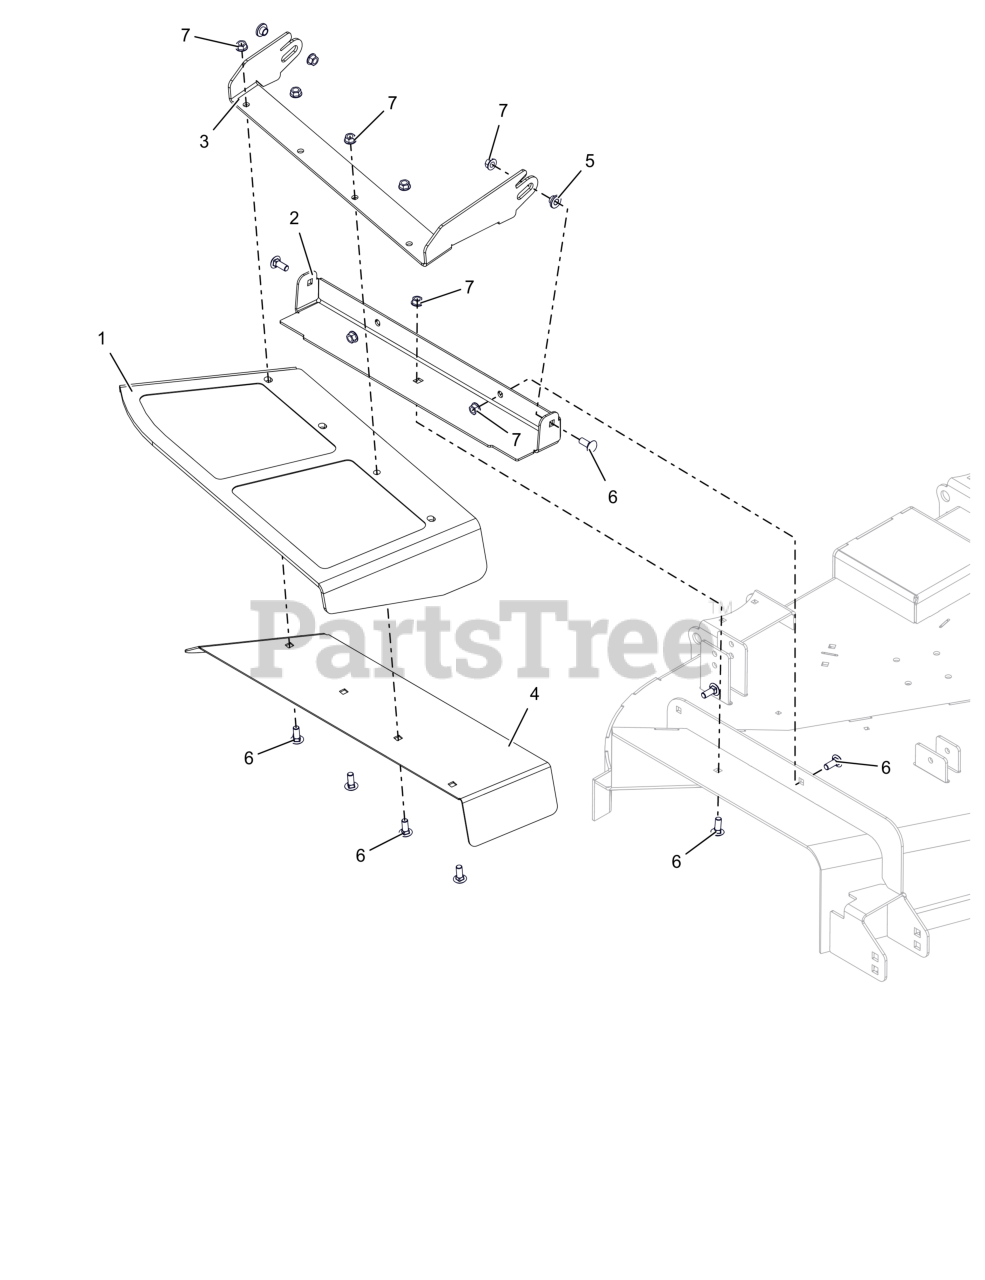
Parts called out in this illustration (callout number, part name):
1	CHUTE, 72" FORMED RUBBER DISCH
2	BASE, 61" DISCH CHUTE MTG BRKT (RED)
3	BRKT, 61" CHUTE MTG (RED)
4	PLATE, 61" DISCH CHUTE CLAMP (RED)
5	BSHG-FLG .385X.500X.875X.406
6	BLT, RHSN .38-16X1.00 G5 ZCC
7	NUT-LK-CTR-FLG .375-16 GF ZCC
